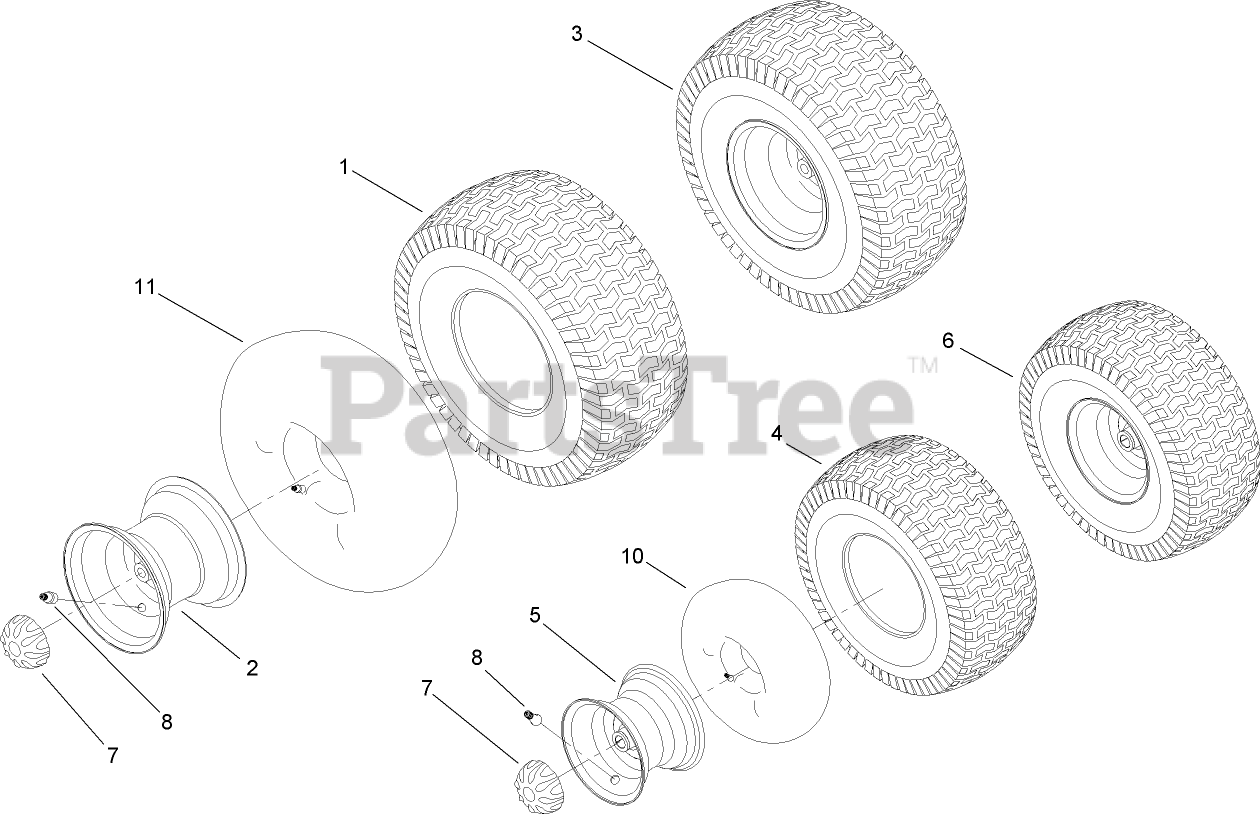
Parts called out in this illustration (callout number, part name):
1	TIRE-TURF
3	WHEEL ASM
4	TIRE-TURF
5	RIM-WHEEL, FRONT
6	WHEEL ASM
7	CAP-HUB
8	VALVE-AIR, TUBELESS
10	TUBE-INNER
11	TUBE-INNER
